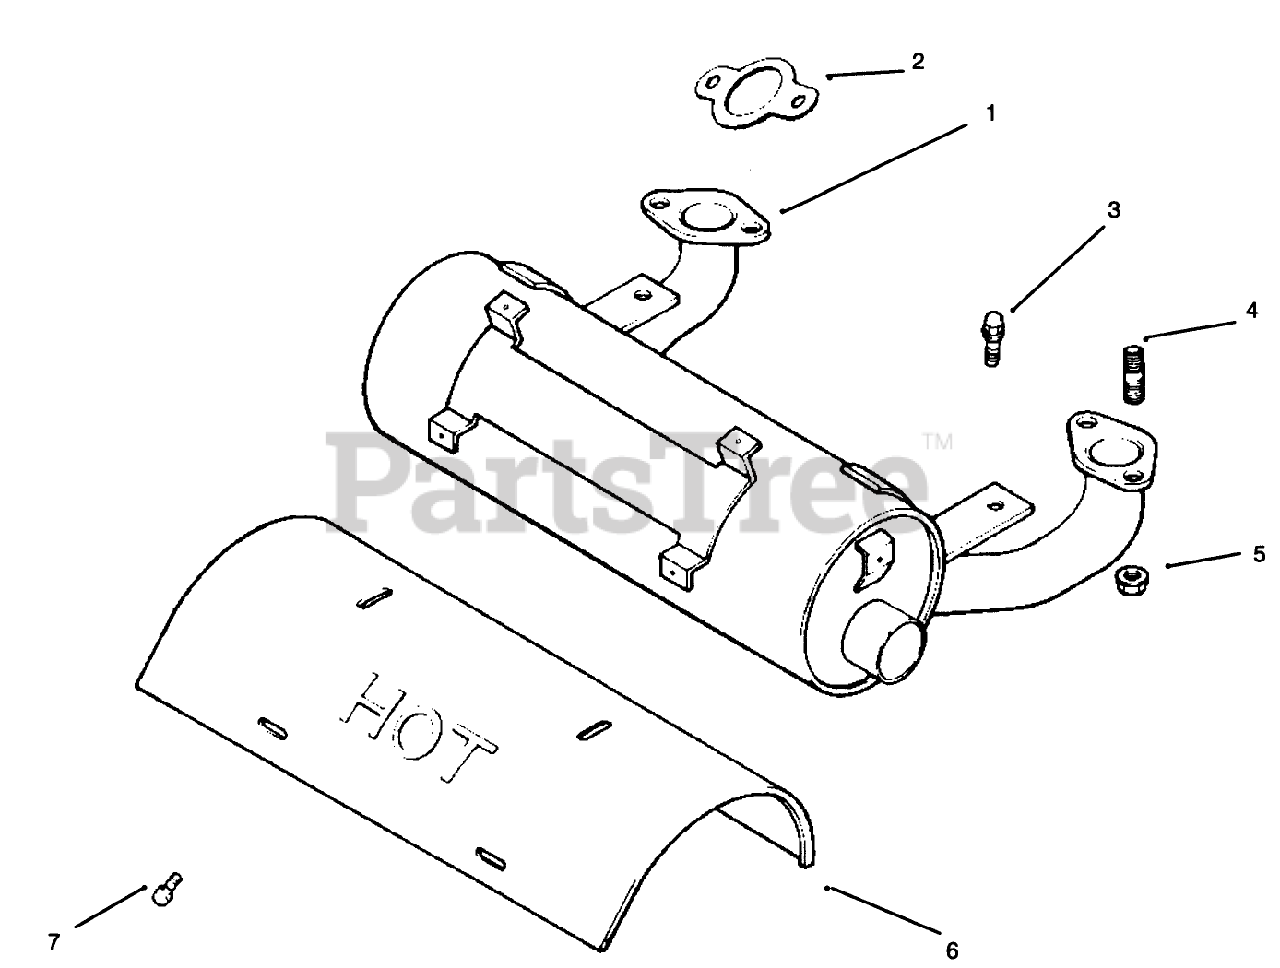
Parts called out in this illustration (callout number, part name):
1	Muffler
2	Gasket-Exhaust
6	Duct-Heat Shield
